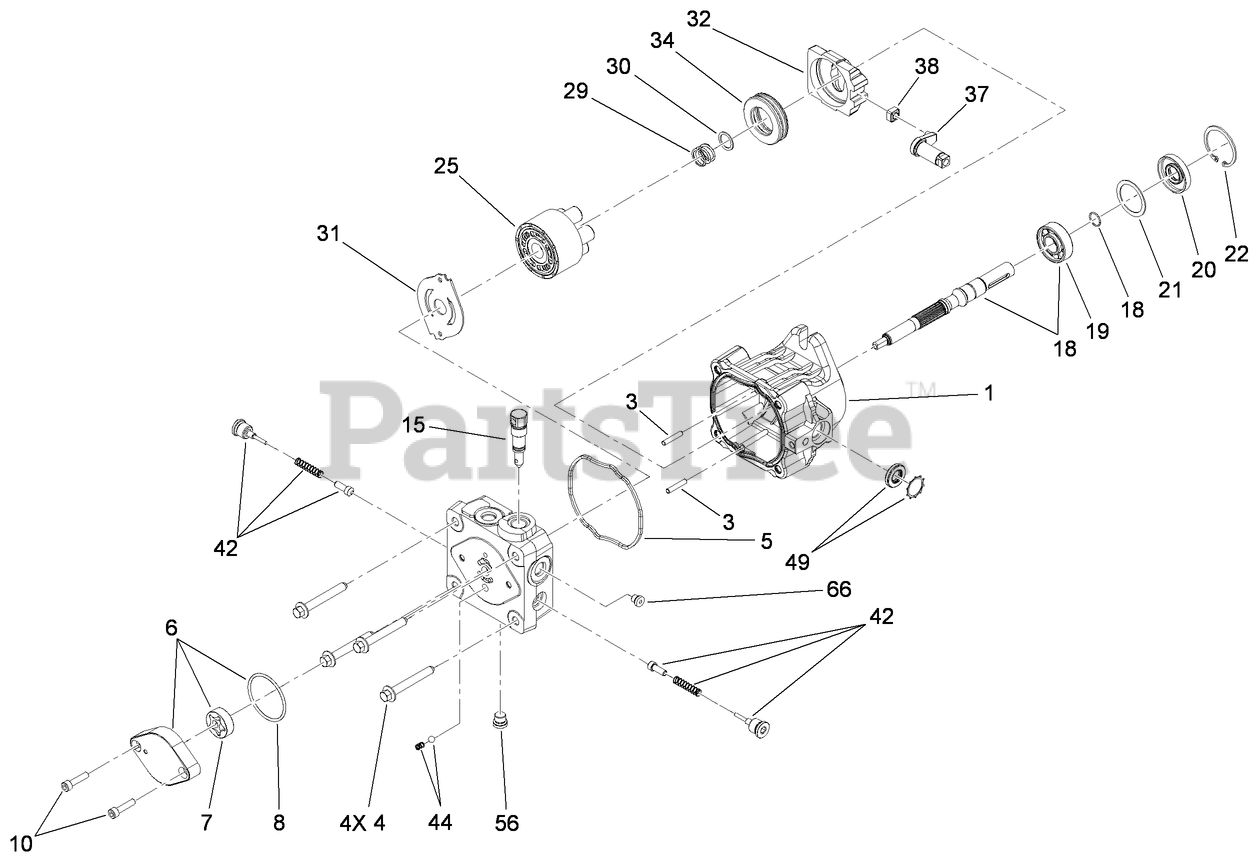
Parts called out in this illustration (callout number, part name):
1	HOUSING KIT
3	PIN-HEADLESS, STRAIGHT
4	BOLT-HF
5	O-RING
6	CHARGE PUMP KIT
7	GEROTOR ASM
8	O-RING
10	CAPSCREW
15	BYPASS VALVE KIT
18	INPUT SHAFT KIT
19	BEARING-BALL
20	SEAL-LIP
21	SPACER
22	RING-RETAINING
25	CYLINDER BLOCK KIT
29	SPRING-BLOCK
30	WASHER-THRUST
31	Plate-Valve
32	SWASHPLATE-VARIABLE
34	BEARING-THRUST
37	ARM-TRUNNION, TAPERED SQUARE
38	GUIDE-SLOT
42	VALVE-CHECK (W/POPPET)
44	CHARGE RELIEF VALVE KIT
49	TRUNNION SEAL KIT
56	PLUG-HSH
66	PLUG-HSH
